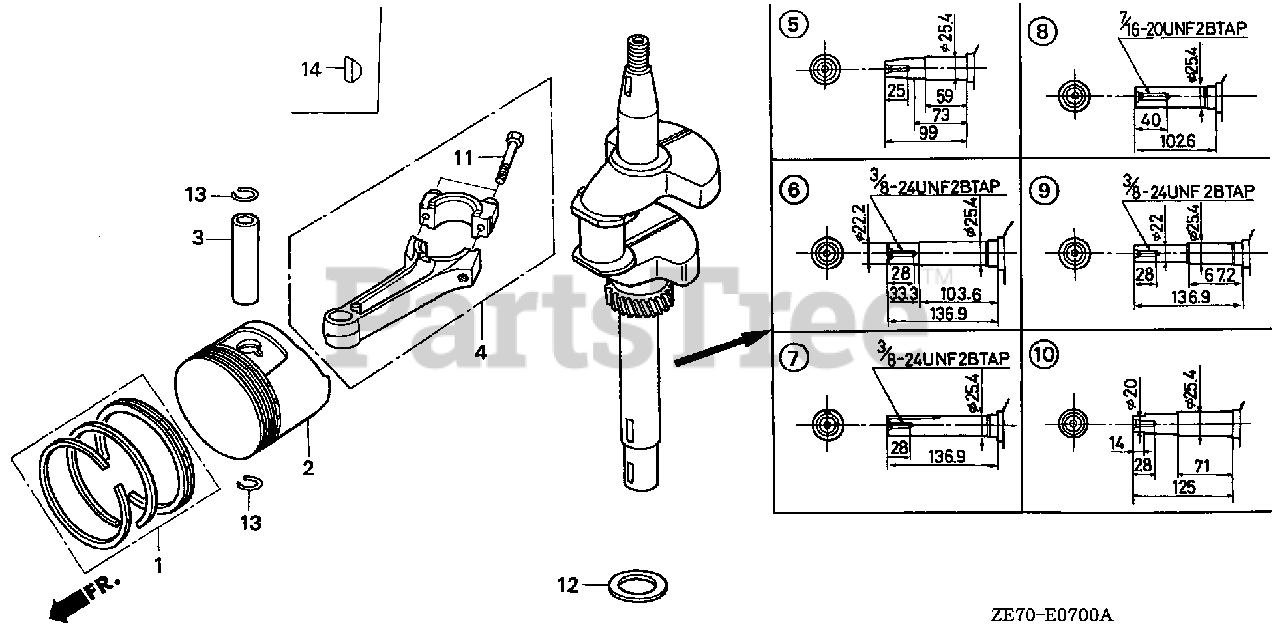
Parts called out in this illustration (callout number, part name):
1	RING SET, PISTON (STD)
1	RING SET, PISTON (OS 0.25)
1	RING SET, PISTON (OS 0.50)
1	RING SET, PISTON (0.75)
2	PISTON (STD)
2	PISTON (OS 0.25)
2	PISTON (OS 0.50)
2	PISTON (0.75)
3	PIN, PISTON
4	ROD ASSY., CONNECTING
4	ROD ASSY., CONNECTING (US 0.25)
9	CRANKSHAFT (HR215 TYPE)
11	BOLT, CONNECTING ROD
12	WASHER, THRUST (25.6MM)
13	CLIP, PISTON PIN (18MM)
